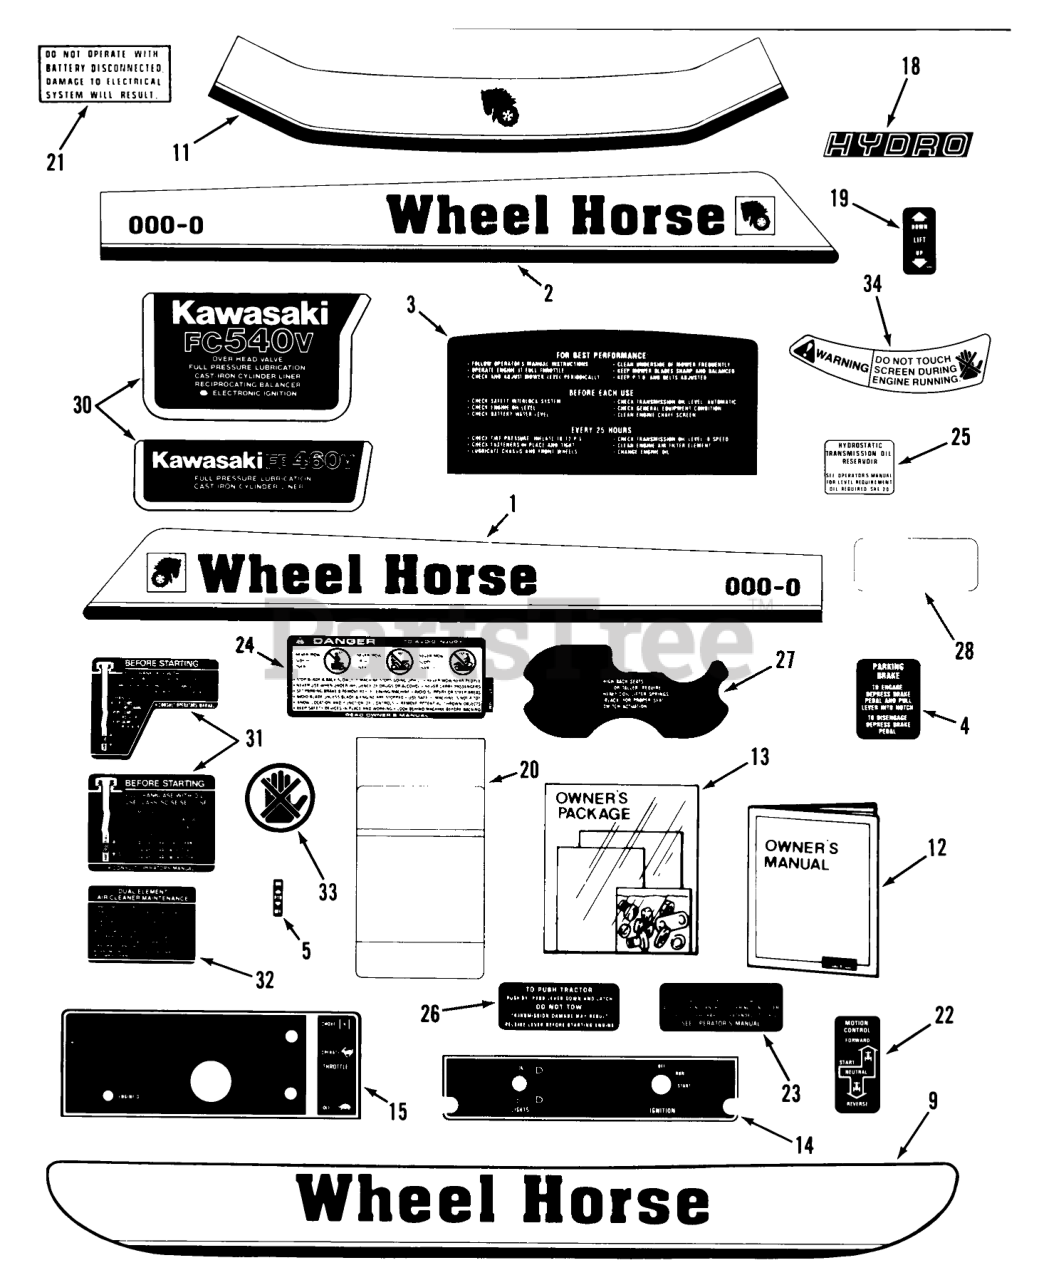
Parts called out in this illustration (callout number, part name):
1	DECAL-HOOD R.H.
2	DECAL-HOOD L.H.
3	DECAL-REAR HOOD
4	DECAL-PARKING, BRAKE
5	DECAL-PTO
9	DECAL-FENDER
11	DECAL-FRONT HOOD
12	Owner-s Manual-Tractor
13	New Tractor Loose Parts Package 252-H
13	New Tractor Loose Parts Package 257-H
14	DECAL BACK PLATE
15	Decal-Dash 252-H
15	DECAL-LOWER DASH
18	DECAL-HYDRO
19	DECAL-LIFT
20	Decal-Maintenance
21	DECAL ELECT SYSTEM
22	DECAL-SPEED CONTROL
23	DECAL-PTO BELT ADJ
24	DECAL-DANGER
25	DECAL-TRANS OIL
26	DECAL-TO PUSH TRAC
27	DECAL-SEAT LIFTER
28	DECAL-OVERLAY
29	Decal-Attac-O-Matic
30	LABEL-BRAND
30	DECAL-BRAND
31	Decal-Engine Oil FB460V (vendor #56031-2249)
31	Decal-Engine Oil FC540V (vendor #56031-2238)
32	Decal-Air Cleaner Maint. (vendor #56031-2191)
33	DECAL-WARNING
34	DECAL-WARNING
